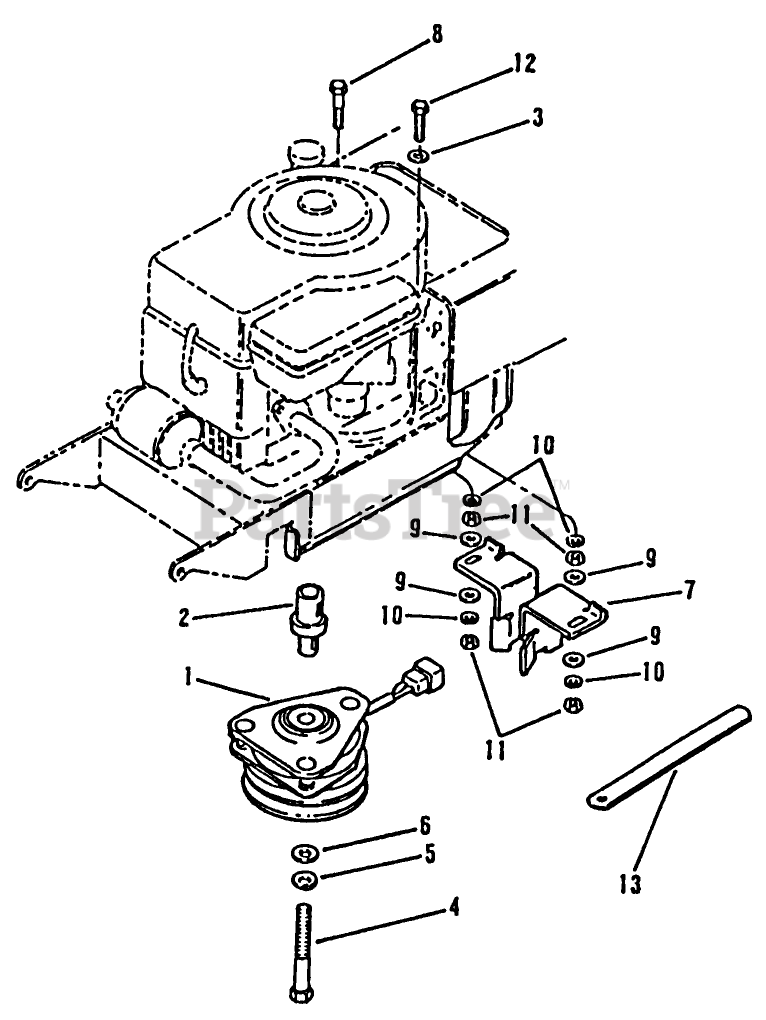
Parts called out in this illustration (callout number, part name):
1	CLUTCH-BRAKE ELECT
2	ADAPTER
4	SCREW-HEXHEAD CAP
